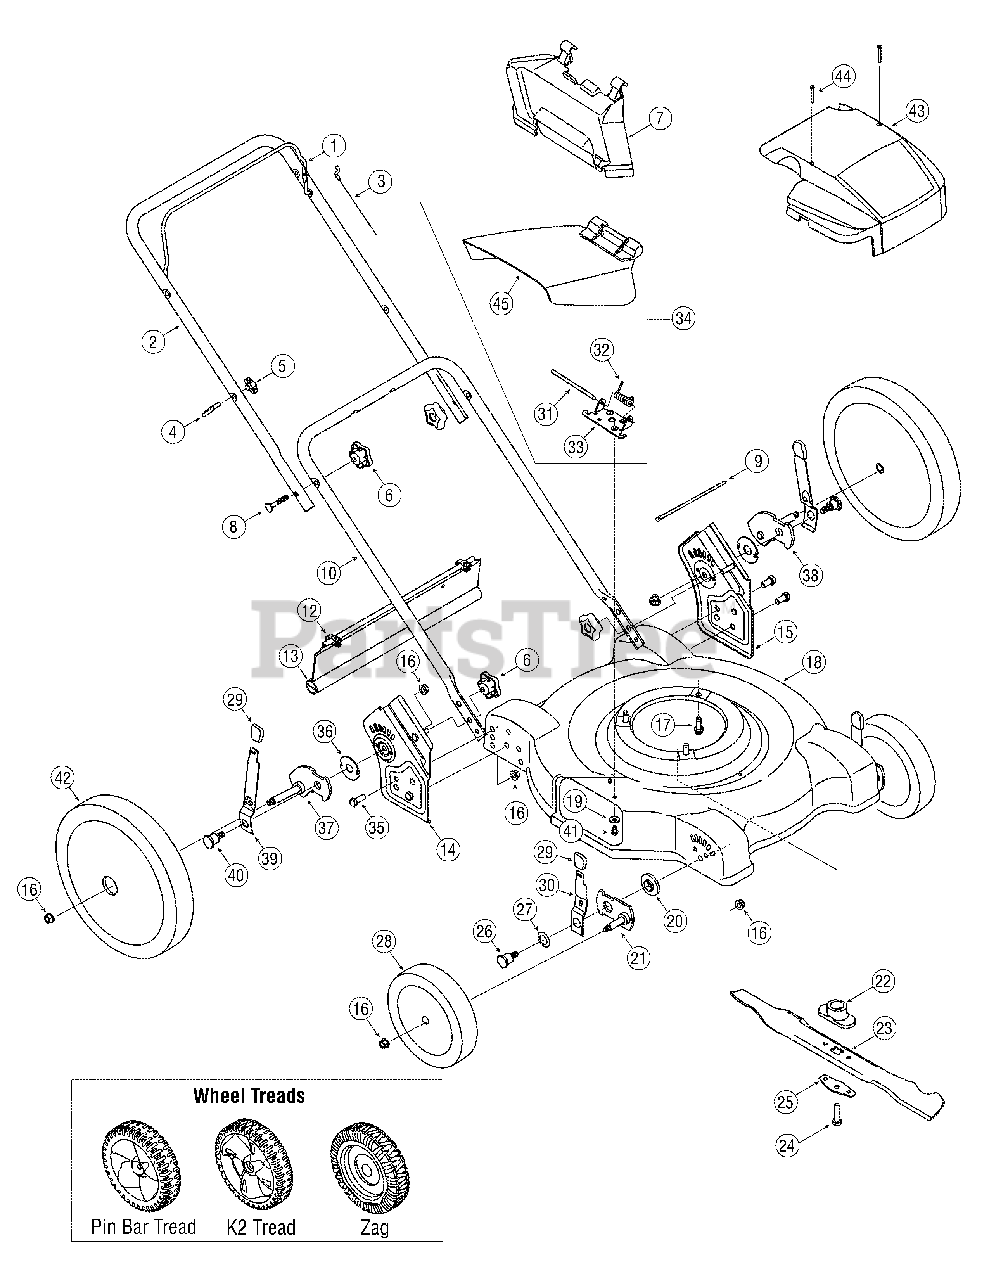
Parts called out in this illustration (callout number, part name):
3	Blade Control Cable - 37.25"
3	Blade Control Cable - 40"
3	Blade Control Cable - 48.25"
4	Eye Bolt
5	Wing Nut
6	Star Knob
7	Mulching Baffle
8	Carriage Bolt 5/16-18 x 2.0
9	Cable Tie
12	Hinge Clip
13	Trail Shield
17	Hex Washer Screw 3/8-16 x 1.0
19	Bell Washer.265 x.75
20	Height Adjuster Bearing
21	Pivot Arm Assembly
22	Blade Adapter
23	22" Mulching Blade
23	22" Standard Blade
24	Hex Cap Screw 3/8-24 x 1.5
25	Blade Bell Support
26	Shoulder Screw 3/8 - 16 x.302
27	Bell Washer.760 ID x 1.25 OD
28	Front Wheel, 7 x 1.8, K2 Bar
28	Front Wheel, 7 x 1.8, Pin Bar
29	Height Adjuster Knob
30	Front Spring Lever
31	Hinge Pin
32	Torsion Spring
33	Deflector Chute Adapter
34	Side Discharge Chute Assembly
35	Hex Cap Screw 3/8-16 x .75
36	Thrust Brg., .688 ID x 1.94 OD
37	Rear Pivot Arm Assembly - RH
38	Rear Pivot Arm Assembly - LH
39	Rear Spring Lever
40	Shoulder Screw 3/8 - 16 x.442
41	Screw 1/4-20 x.50
42	Rear Wheel, 12 x 1.8, K2 Bar
42	Rear Wheel, 12 x 1.8, Pin Bar
43	Engine Shroud
44	Screw, #8-18 x 1.25
